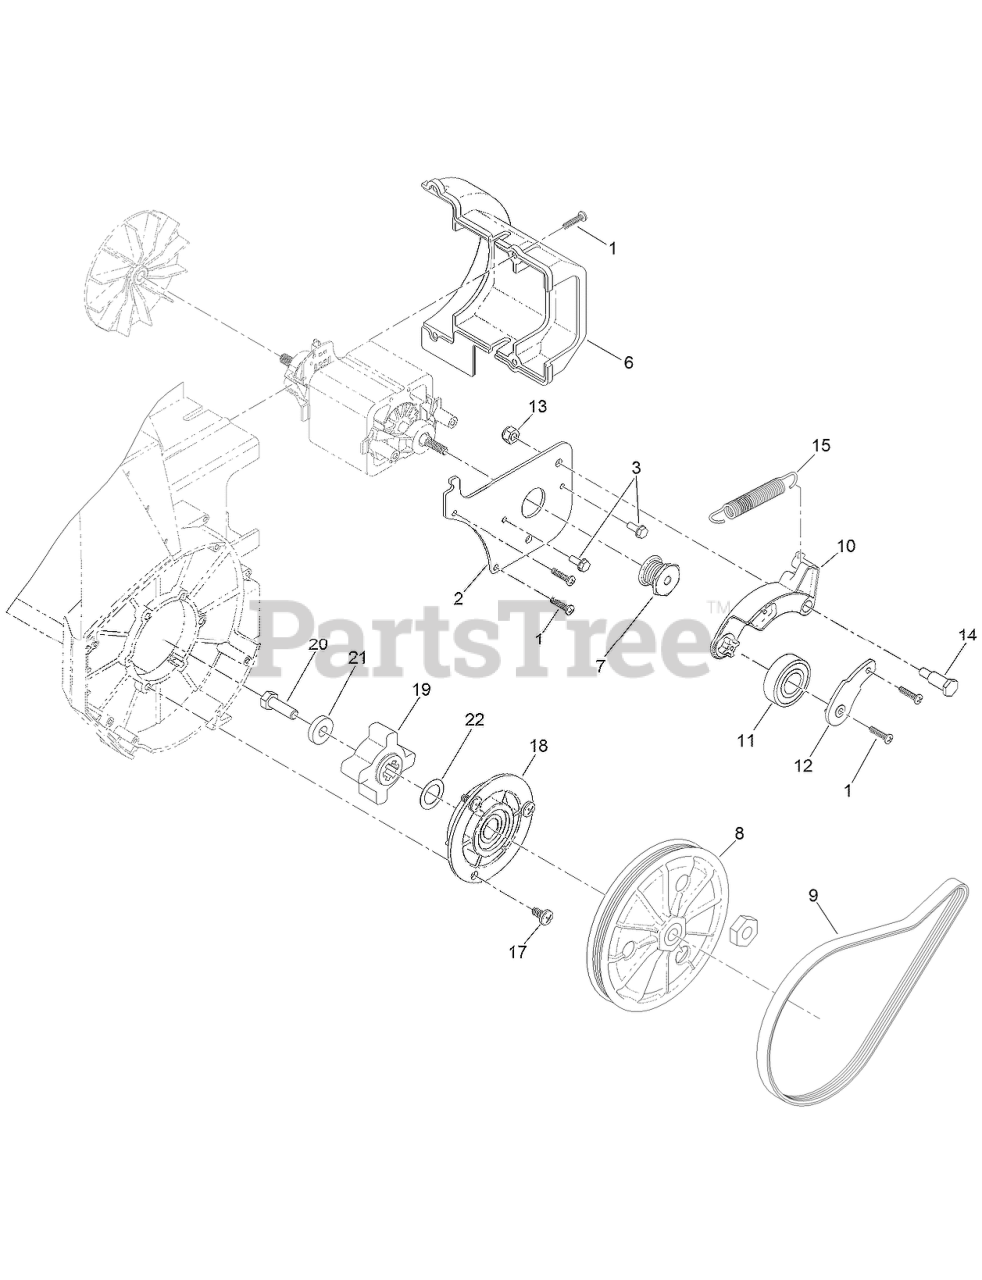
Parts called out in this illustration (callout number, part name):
1	SCREW-PPH
2	PLATE-MOTOR
3	SCREW-HWH
6	COVER-MOTOR
7	PULLEY-DRIVE
8	PULLEY ASM
9	BELT-DRIVE
10	ARM-IDLER
11	BEARING-BALL
12	RETAINER-IDLER
13	NUT-LOCK, NI
14	BOLT-SHOULDER
15	SPRING-IDLER
17	SCREW-SEAT, SWITCH
18	PILLOW BLOCK ASM
19	COUPLER-PULLEY
20	SCREW-HH
21	SPACER
22	WASHER
